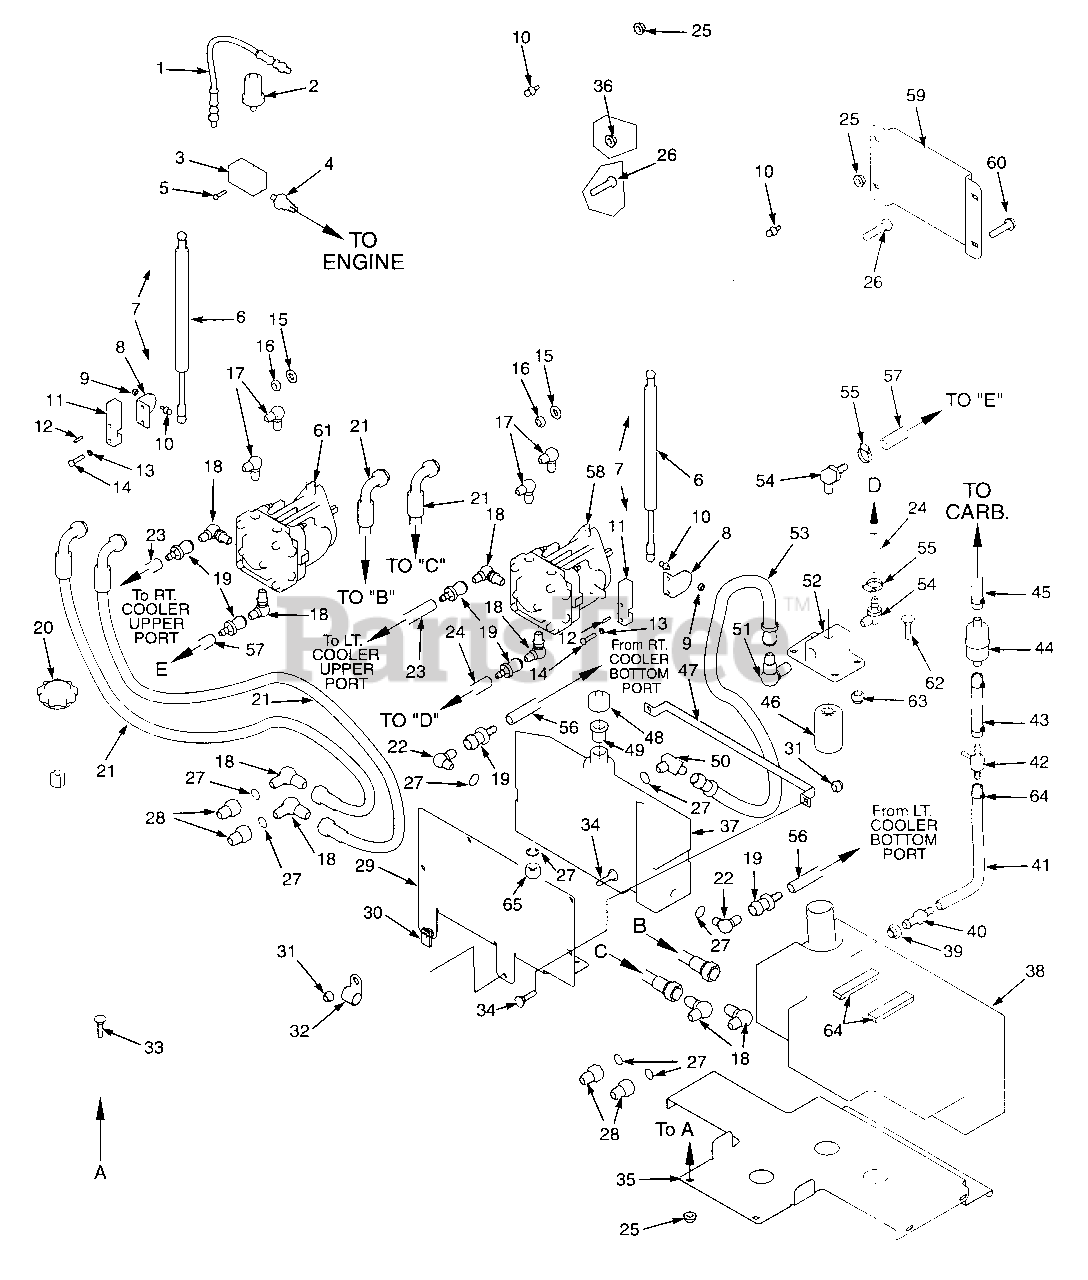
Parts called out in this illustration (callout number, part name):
1	Hose, Oil Pressure Sender
2	Oil Pressure Sender
3	Oil Manifold
4	Switch, Low Oil Pressure
5	Bolt, Hex Head 1/4-20 x 2"
6	Gas Damper
7	Spring Clip
8	Clamp Plate, Pump Control
9	Locknut, 5/16-18 CTR
10	Ball Stud
11	Block, Pump Control
12	Pin, Spring .210 x 1.0"
13	Lockwasher, 1/4 Spring
14	Bolt, Hex Head 1/4-20 x 1.50"
15	Flatwasher, 1/2 (.531 x .062 x .095)
16	Nut, 1/2-13 Elastic Stop
17	Elbow, 90 Degree, 7/8-14 THD
18	Elbow, 90 Degree,3/4-16 THD
19	Coupling, 3/4-16 THD
20	Cap, Fuel Tank W/Gauge
21	Hose Assembly, Wheel Motor
22	Elbow, 90 Degree, 9/16-18 JIC x 9/16 O-Ring
23	Hose, 3/8" ID. Pushlock - 25.0"
24	Hose, 3/8" ID. Pushlock - 10.25"
25	Nut, 5/16-18 Serrated Flange
26	Bolt, Hex Head 1/4-20 x 2.0"
27	O-Ring
28	Bushing, 7/8-14 JIC x 3/4-16 O-Ring
29	Support Bracket, Hydraulic Tank
30	U-Nut, 1/4-20
31	Nut, Hex Elastic Stop 1/4-20
32	Hose Clamp
33	Bolt, Carriage 5/16-18 x 3/4"
34	Bolt, Carriage 1/4-20 x 1.0"
35	Support Bracket, Fuel Tank
36	Nut, Hex 1/4-20 Serrated Flange
37	Oil Reservoir Assembly
38	Fuel Tank Assembly
39	Bushing
40	Hose Fitting
41	Fuel Hose, 1/4" ID - 10"
42	Valve, Shutoff
43	Fuel Hose, 1/4" ID. - 2"
44	Fuel Filter
45	Fuel Hose To Carb.
46	Oil Filter
47	Strap, Hydraulic Tank
48	Cap, Hydraulic Tank
49	Insert, Filler Neck
50	Elbow, 45 Degree 3/4-16 JIC x 3/4-16 O-Ring
51	Elbow, 45 Degree 1/2 NPT x 3/4 JIC
52	Oil Filter Base
53	Hose Assembly
54	Elbow, 90 Degree-1/4 NPT x 3/8 Hose
55	Clamp, Hose 1/2"
56	Hose, 3/8 ID. Pushlock - 14.50"
57	Hose, 3/8 ID Pushlock - 38.0"
58	Pump, BDP-21L-305 LH
59	Rear Cover
60	Bolt, Carriage 5/16-18 x .75"
61	Pump, BDP-21L-403 RH
62	Bolt, Carriage 5/16-18 x 1.0"
63	Nut, Hex Elastic Stop 5/16-18
64	Pad, Rubber
65	Plug, 3/4-16" "O" Ring
